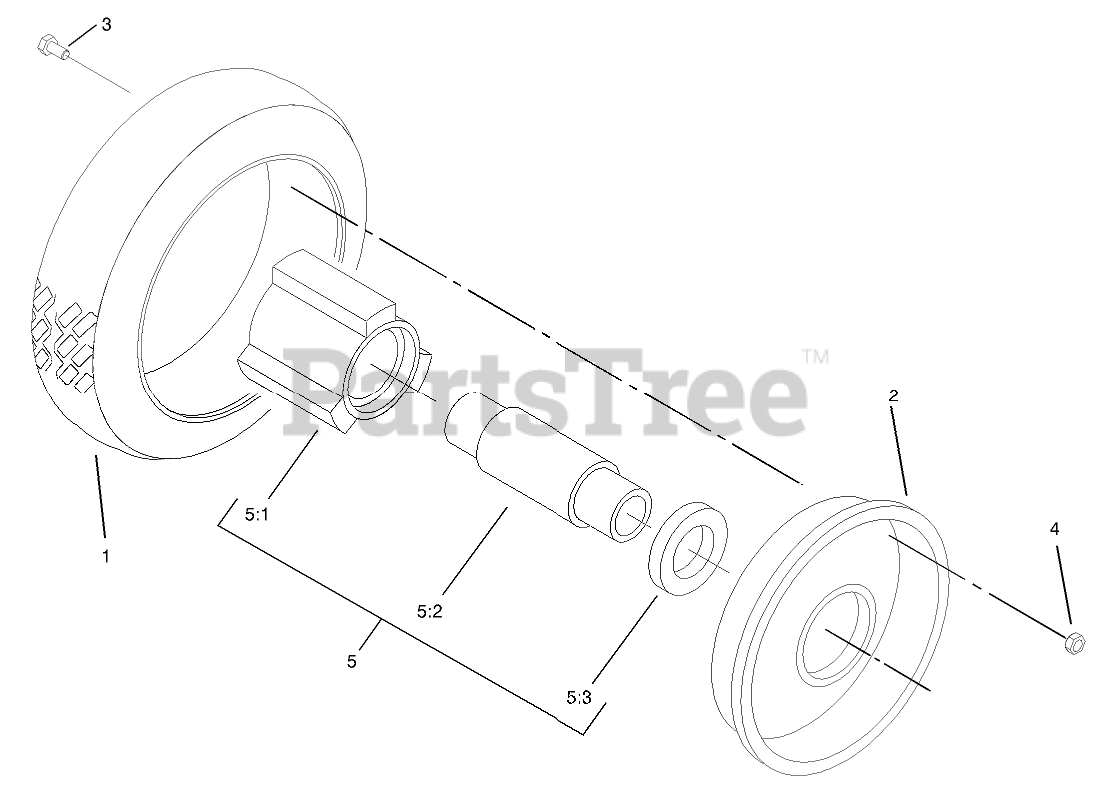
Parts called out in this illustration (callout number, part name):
2	PLATE-WHEEL, HALF
3	SCREW-HH
4	NUT-LOCK, NI
5	HUB and BEARING ASM
5:1	HUB-BEARING
5:2	SPACER-BEARING
5:3	BEARING-WHEEL
